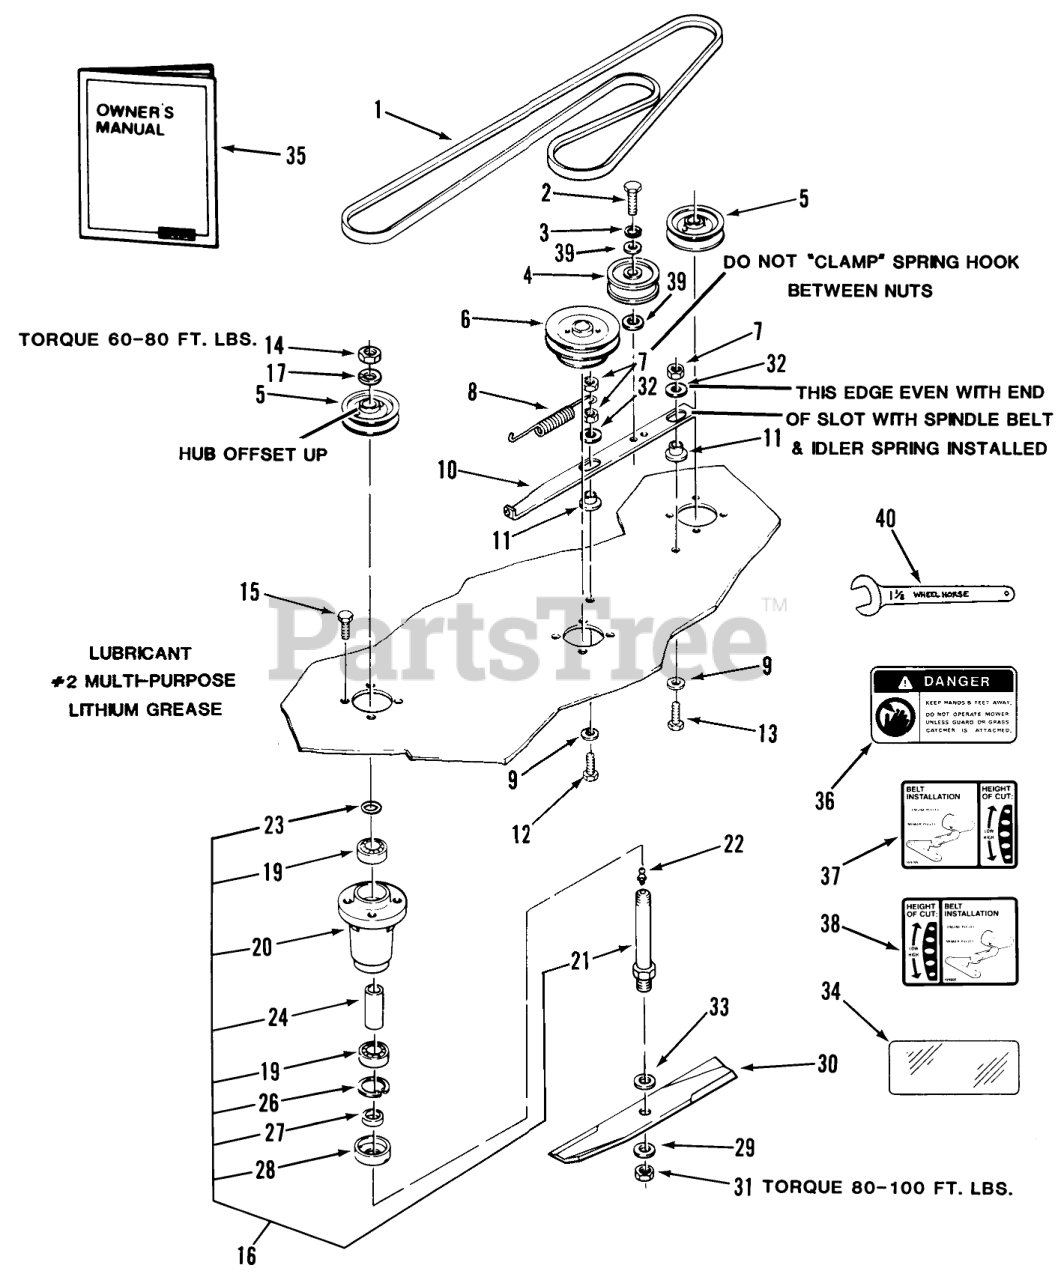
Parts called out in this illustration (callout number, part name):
1	V-BELT
1	V BELT
2	Bolt
3	LOCKWASHER
4	Pulley
4	Idler Pulley
5	PULLEY-BLADE, DRIVE
5	PULLEY
6	PULLEY-MOWER, 48IN
6	PULLEY
7	NUT
8	SPRING-EXTENSION
9	WASHER
10	BAR-IDLER SUPPORT
11	SPACER-BUSHING
12	Bolt
13	Bolt
14	Jam Nut
15	Bolt
16	Spindle Assembly
17	Lockwasher
19	BEARING-BALL
20	HOUSING-SPINDLE
21	SHAFT-SPINDLE
22	Zerk
23	O RING
26	Ring-Snap
27	SPACER-BLADE
28	CUP-SPINDLE
29	Washer
30	BLADE KIT-48 SIDE
30	BLADE KIT-42 SIDE
30	BLADE KIT
31	Nut-Jam
32	WASHER
33	Washer
33	SpeciaI Washer
34	DECAL-OVERLAY
35	Operating and Maintenance Instruction
36	Danger Decal
37	DECAL-HEIGHT & BELT
38	DECAL-HEIGHT & BELT
39	Washer
40	Spindle Wrench
